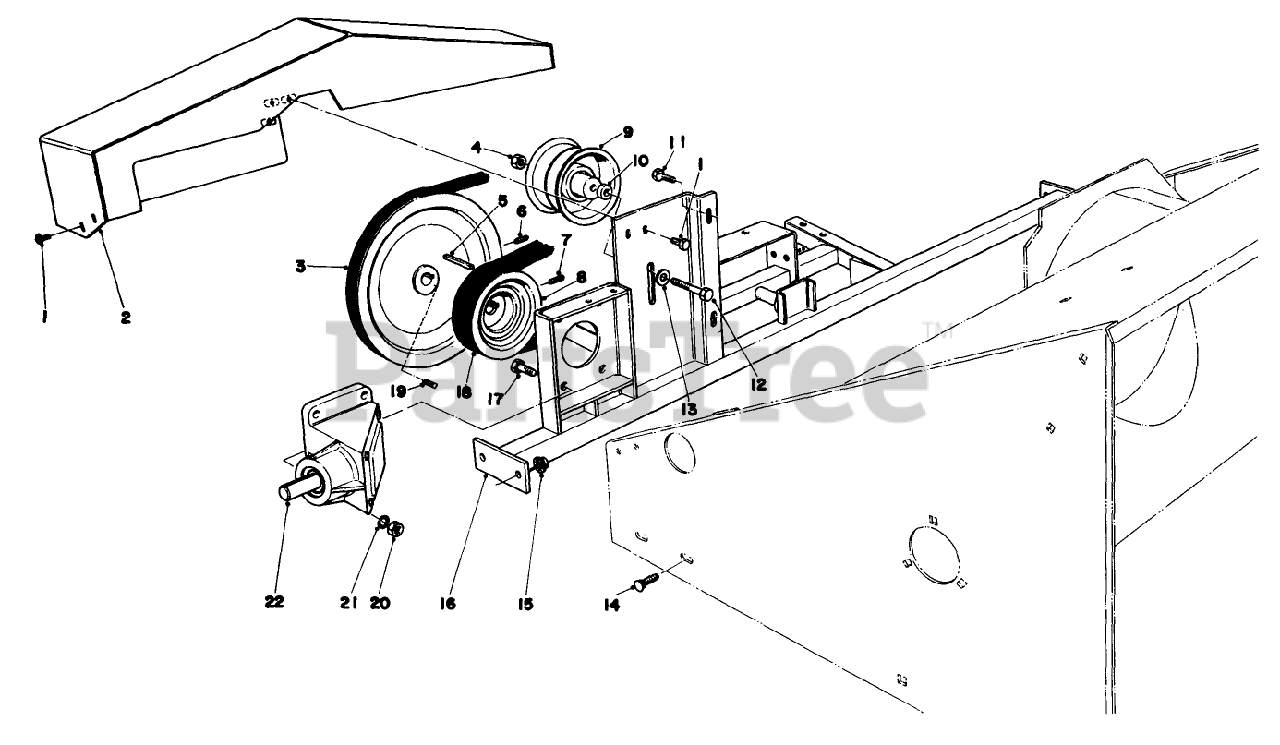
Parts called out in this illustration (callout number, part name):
1	SCREW-HHF
2	BELT SHIELD WA
3	SHEAVE 60014
4	NUT-LOCK, CONE
6	SCREW-SQH
7	SCREW-SET, SQH
8	PULLEY
9	Idler Pulley
10	IDLER SPACER
11	SCREW-HH
12	SCREW-HH
13	WASHER-FLAT
14	SCREW-CARR
15	NUT-HHF, WHIZ
16	Cross Brace
17	SCREW-HH
18	V-BELT
19	SCREW-SET, SQH
20	NUT-HEX
21	WASHER-LOCK
22	Gear Box Assembly
